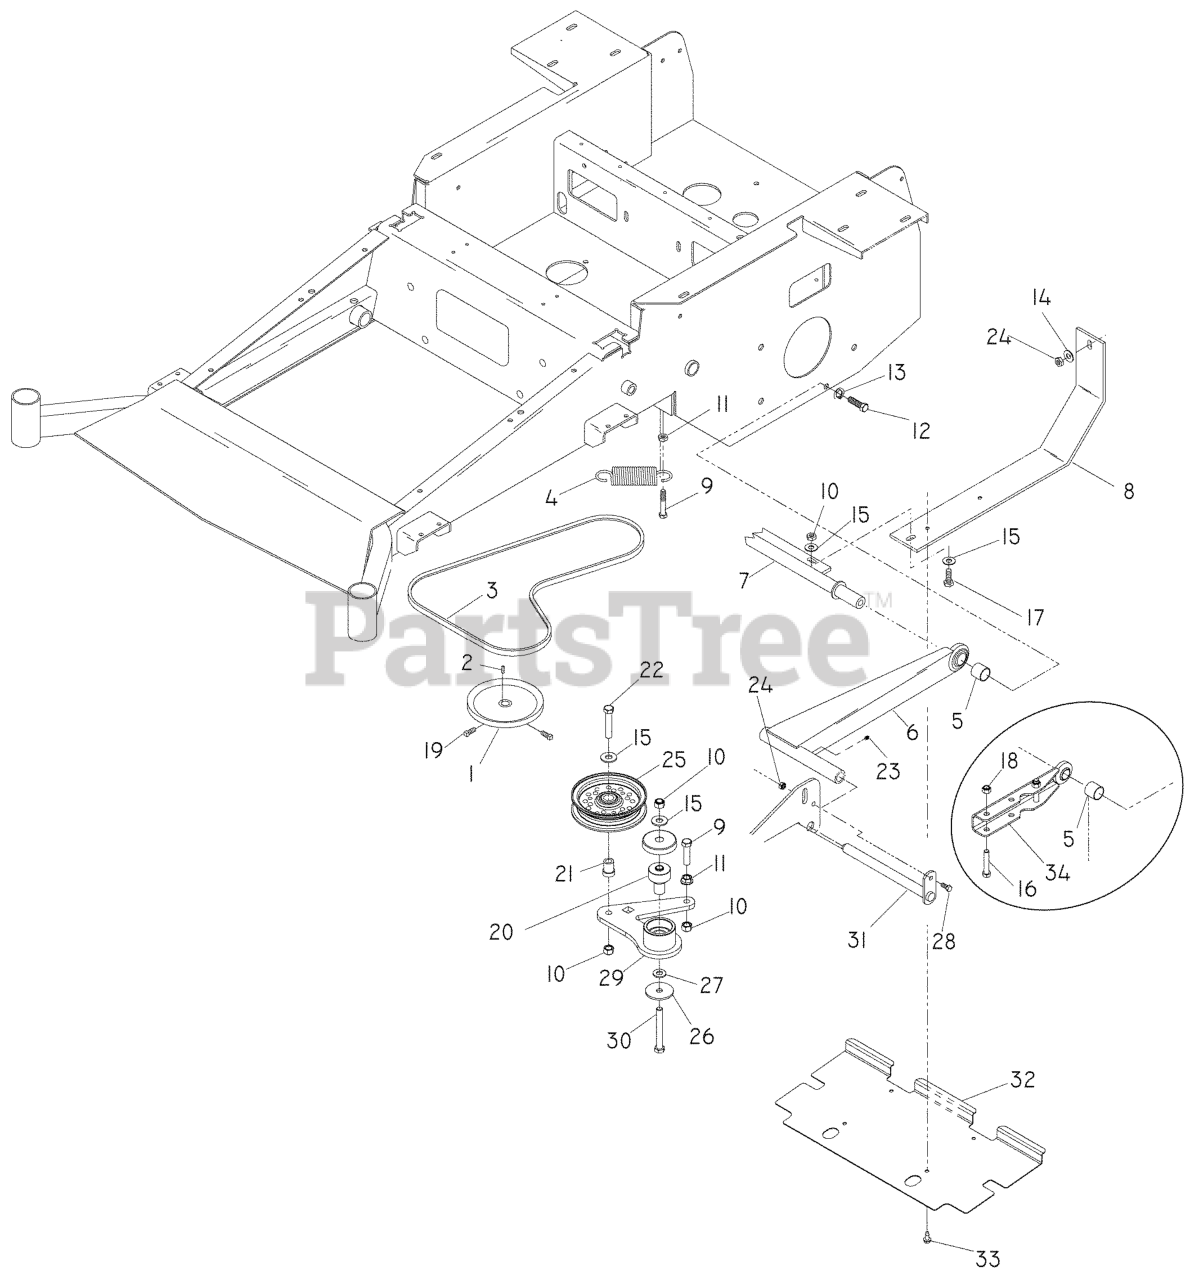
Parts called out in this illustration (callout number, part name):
2	KEY 5 MM SQ X 25 MM
3	PUMP BELT
5	SPACER, STRUT
7	CROSS SHAFT, STRUT - BLK
8	SKID PLATE
9	HCS 3/8C X 1 1/2
10	NUT 3/8-16 NYLOC
11	NUT 3/8C WHIZ
12	BLADE BOLT/WASHER
13	WASHER 7/16 LOCK
14	WASHER 5/16 FLAT
15	WASHER 3/8 FLAT
16	HCS 1/2C X 3 1/4
17	HCS 3/8-16X1.GRD.5.ZD
18	NUT 1/2-13 HEX NYLOC ZD
19	SCREW 5/16C X 5/8 SQ HEAD
20	PIVOT, BEARING
21	BUSHING, IDLER FLANGE
22	HCS 3/8C X 2
23	ZERK
24	NUT 5/16 NYLOC
25	IDLER PULLEY
26	WASHER, 3/8 SPEC
27	WASHER 3/8 SAE FLAT
28	HCS 5/16C X 1
29	ARM, IDLER - W/BEARINGS
30	HCS 3/8C X 3
32	REAR DEBRIS SHIELD
33	BOLT 3/8-16 X 1.0
34	STRUT WELDMENT, REAR
